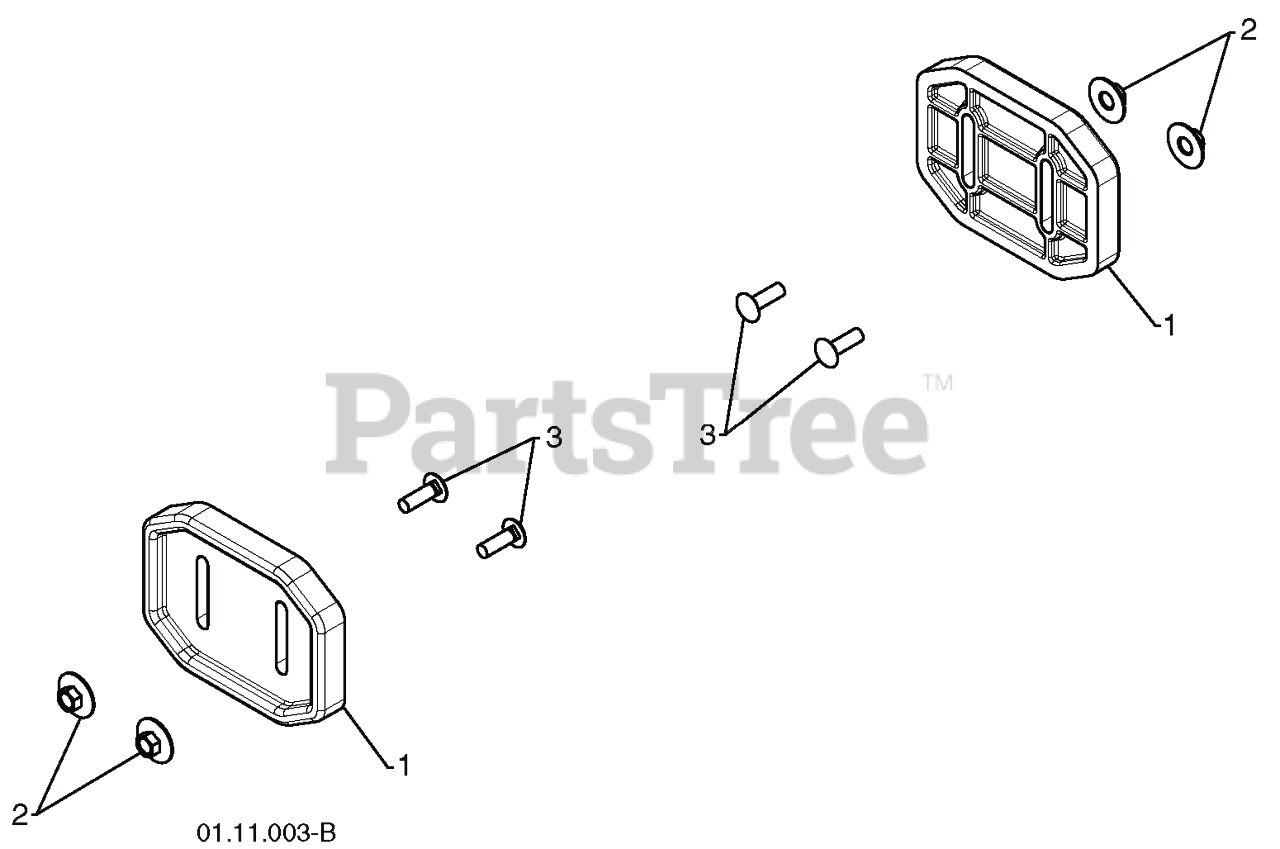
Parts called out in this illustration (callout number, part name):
1	SKID.PLATE.PLASTIC.
2	NUT.FLANGE.HEX.5/16X18.BLACK
3	BOLT.CARRIAGE.5/16-18
